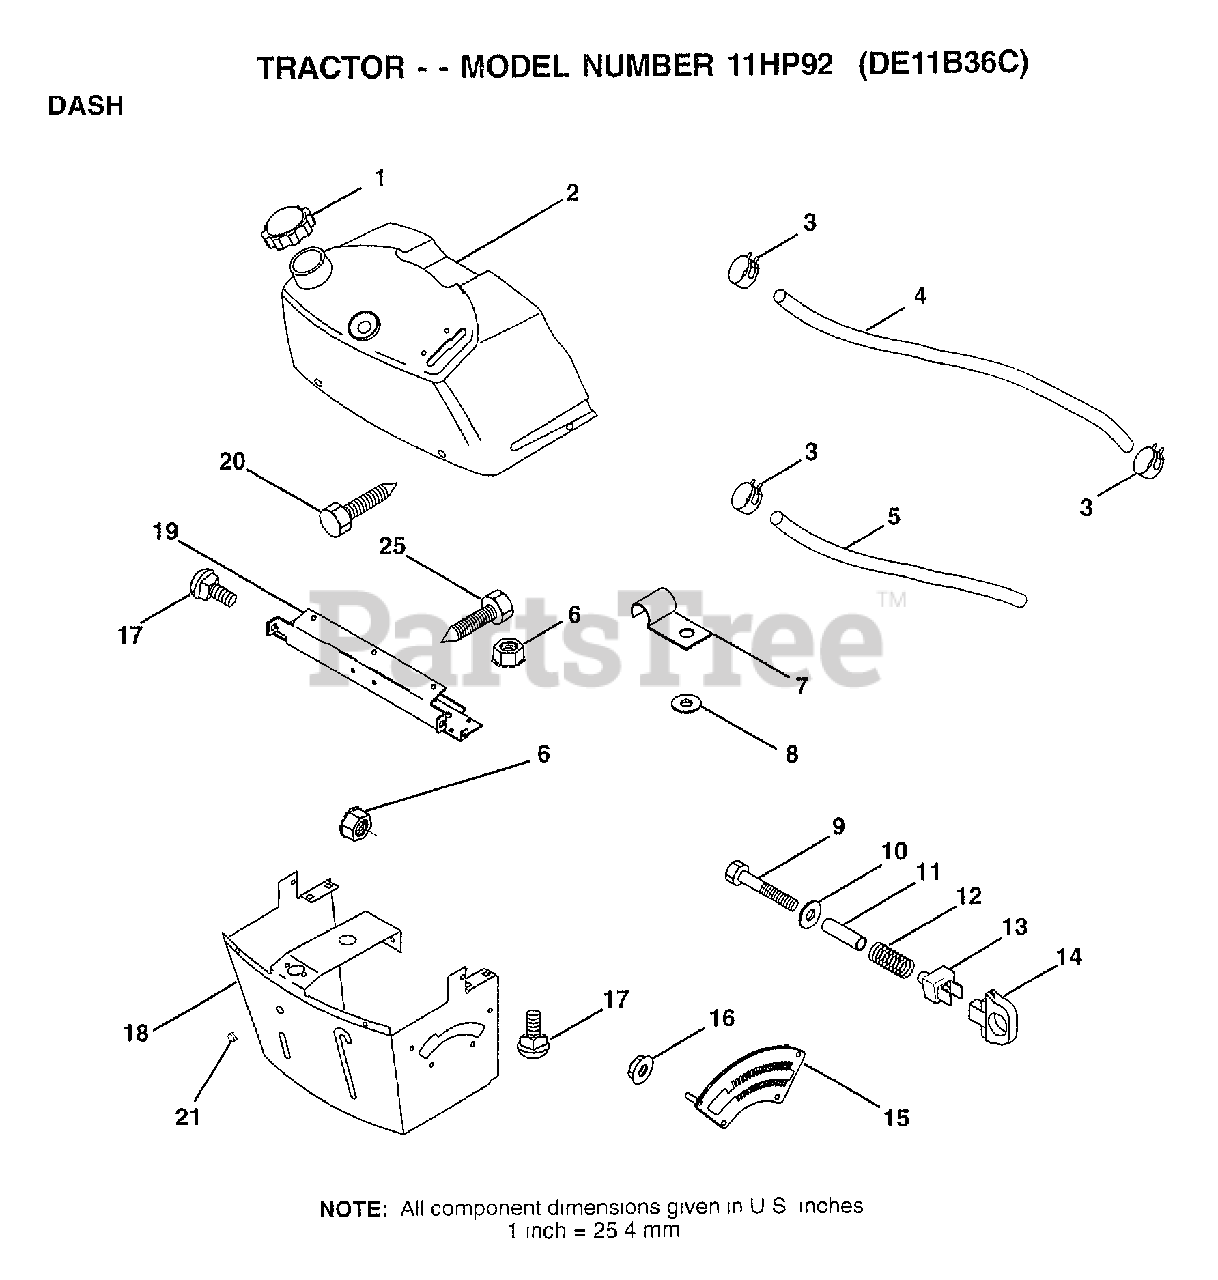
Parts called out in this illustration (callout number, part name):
1	CAP BLK FUEL LR
2	TANK.ASM.DASH.LR
3	HOSE CLAMP
5	FUEL LINE T
6	NUT HXKEP 1/4X20
7	CLIP T
8	WASHER PM
9	BOLT
11	SPACER SPLIT
12	SPRING M
13	"KNOB,HGT RETAINER"
14	KNOB
15	ADJUSTER QUAD
16	NUT
17	BOLT
18	SUPT ASSY DASH
19	CROSS BRACE
20	SCREW.1/4-20X1/2
21	PLUG DOME
25	SCREW LT
